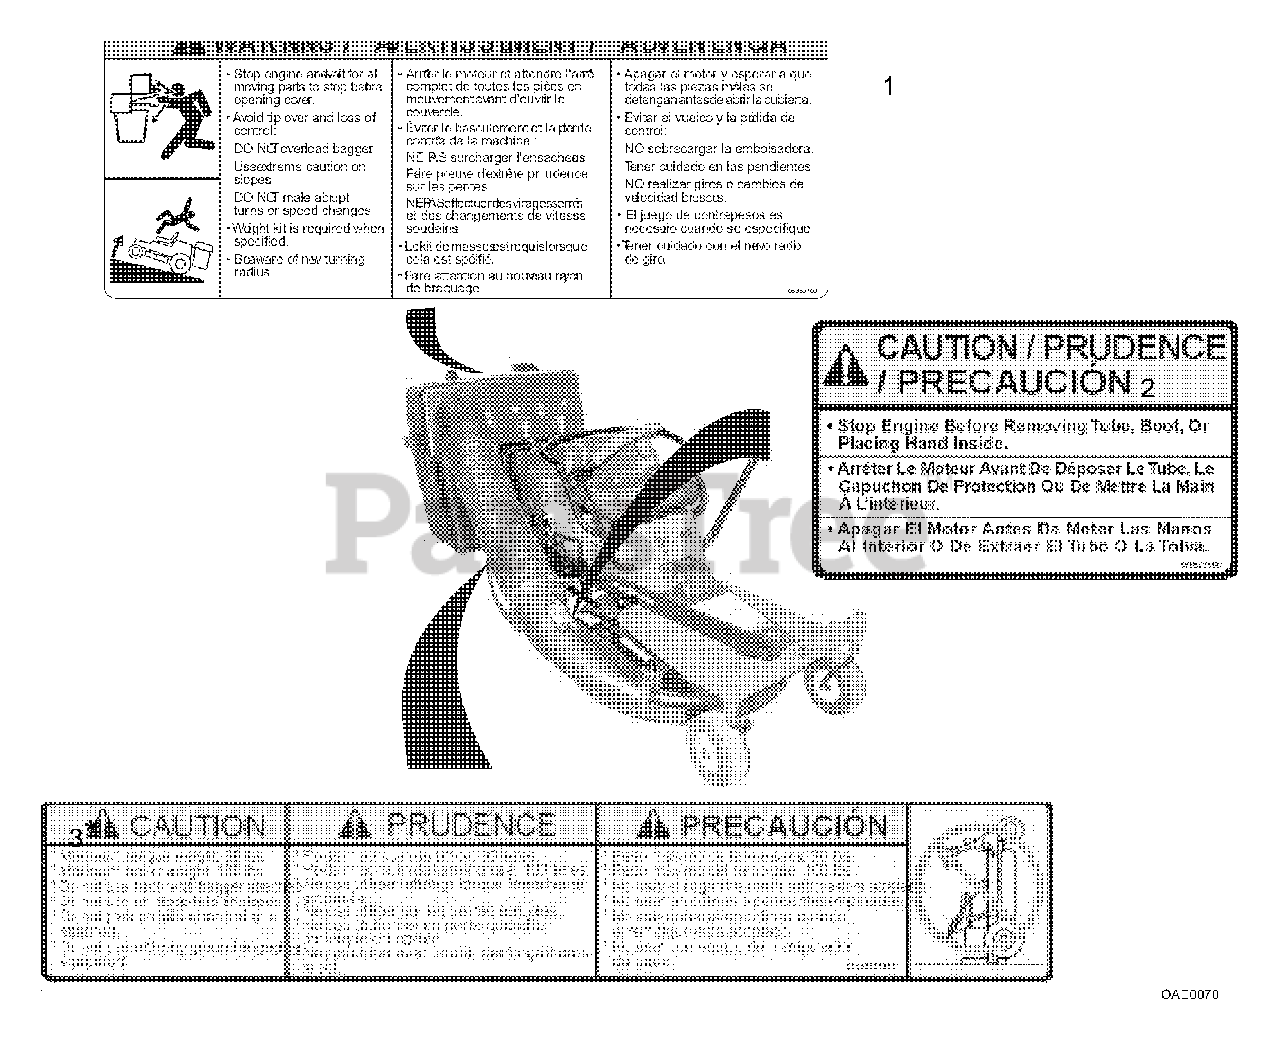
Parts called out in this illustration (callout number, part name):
1	Decal, Bagger Cover Warning
2	Decal, Boot Caution
3	Decal-Hitch 100#
